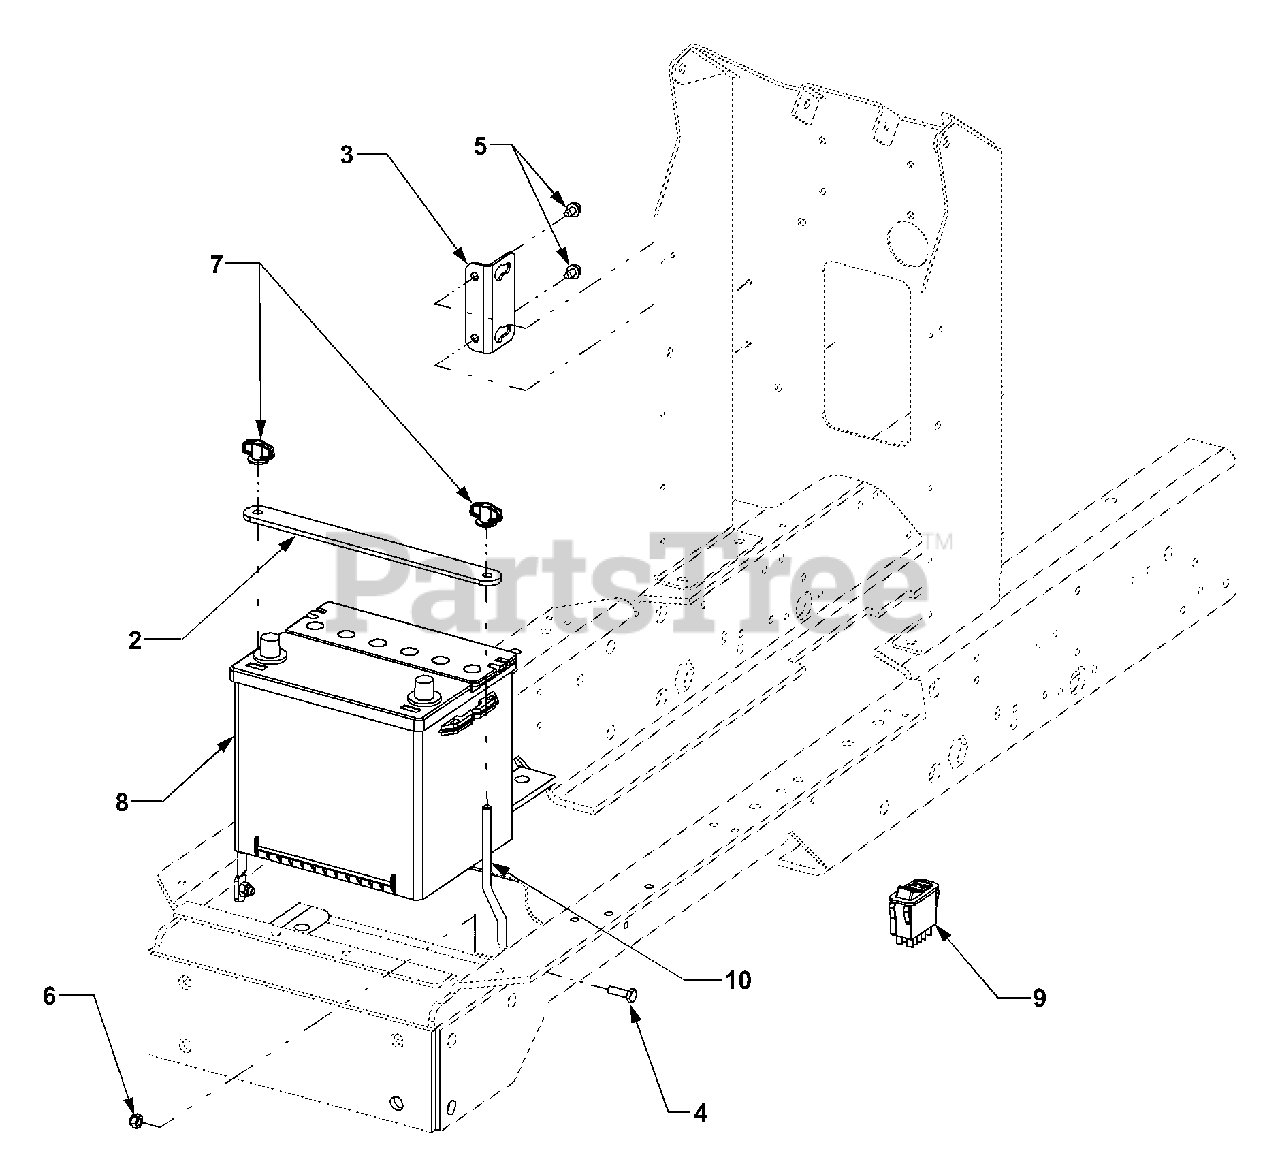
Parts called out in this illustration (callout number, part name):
2	Strap, Battery Holddown
5	Screw, Hex Wash Hd. Tapp 1/4-20 x .5
6	Nut, Hex Nylon Insert Lock, 1/4-20
7	Nut, Wing w/Bell Washer, 5/16-18
8	Battery, 500 cca Dry
9	Switch, PTO Reverse Override
10	Rod, Battery Holddown
